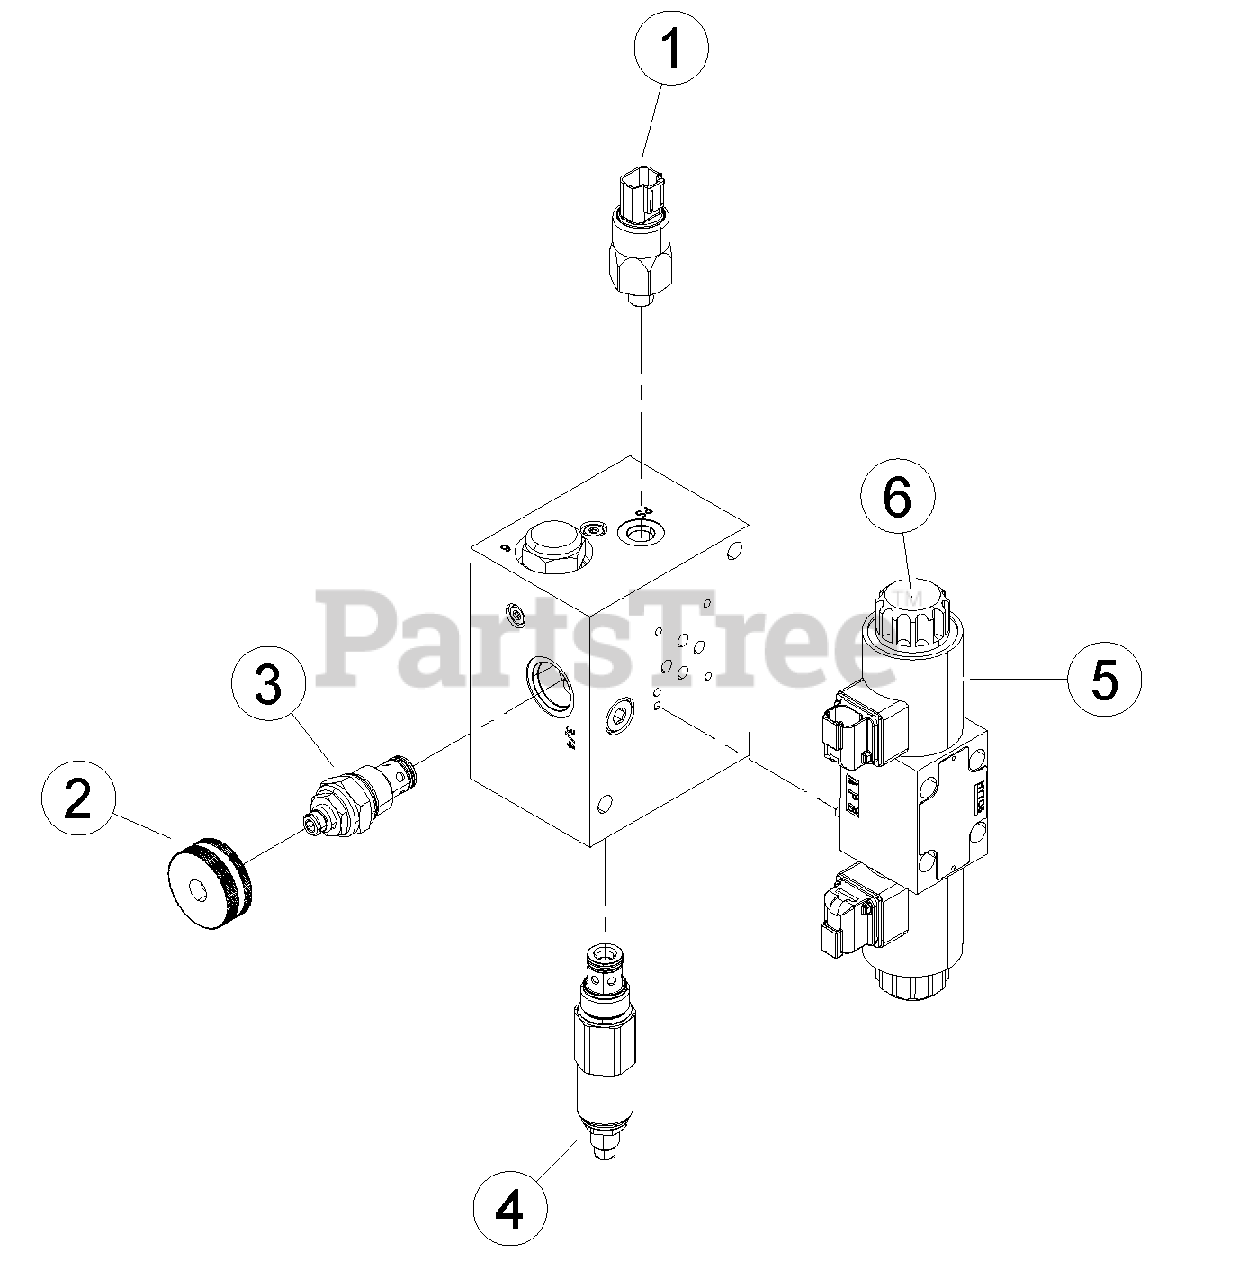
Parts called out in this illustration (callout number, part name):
1	SWITCH, PRESSURE GC
2	KIT, VALVE KNOB
3	VALVE, NEEDLE - 10 MOUNT
4	VALVE, DIFFERENTIAL SENSING
5	COIL, SOLENOID
6	NUT, COIL SOLENOID
